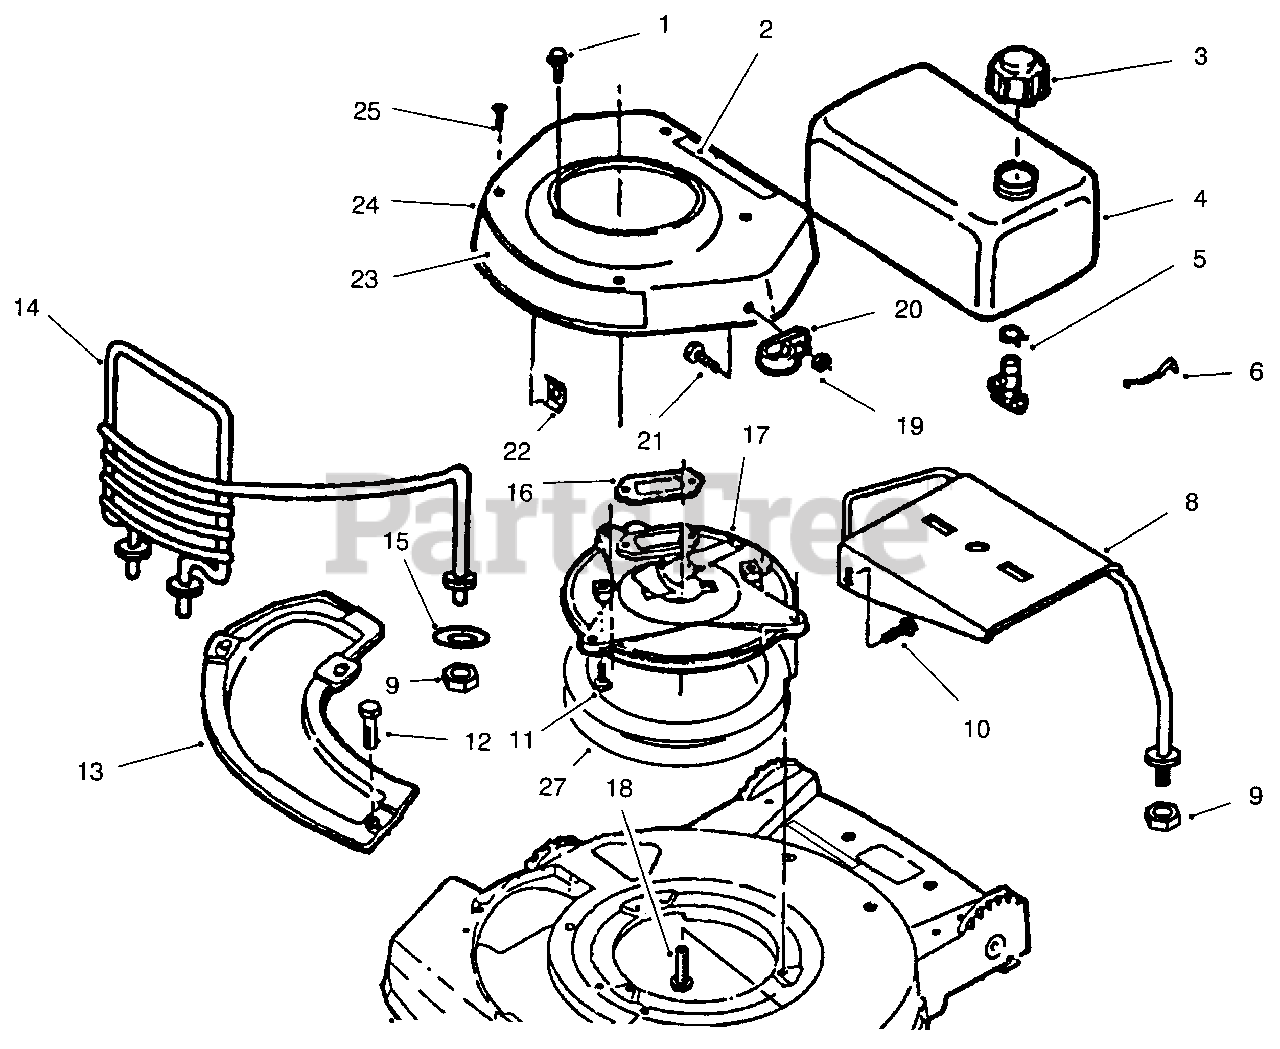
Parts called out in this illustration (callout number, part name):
1	Screw-Starter
2	Decal-Mixture, Fuel
3	Assembly-Cap, Fuel
4	Tank-Fuel
5	Clamp-Valve to Tank
6	Spring-Mount., Fuel Tank
7	Valve & Screen-Shut-Off
8	Bracket-Tank, Fuel
10	Screw-Hex Hd. Cap
11	Screw-Muffler Plate to Block
12	Screw-Hex Hd.
13	Plate-Cover
14	Guard-Engine
16	Gasket-Exhaust
17	Plate-Muffler
18	Screw-Muffler Plate to Housing
19	Nut-Lock
21	Screw-Clamp to Shroud
22	Retainer-Applique
23	Applique
25	Screw-Shroud to Base
27	Plate-Engine
